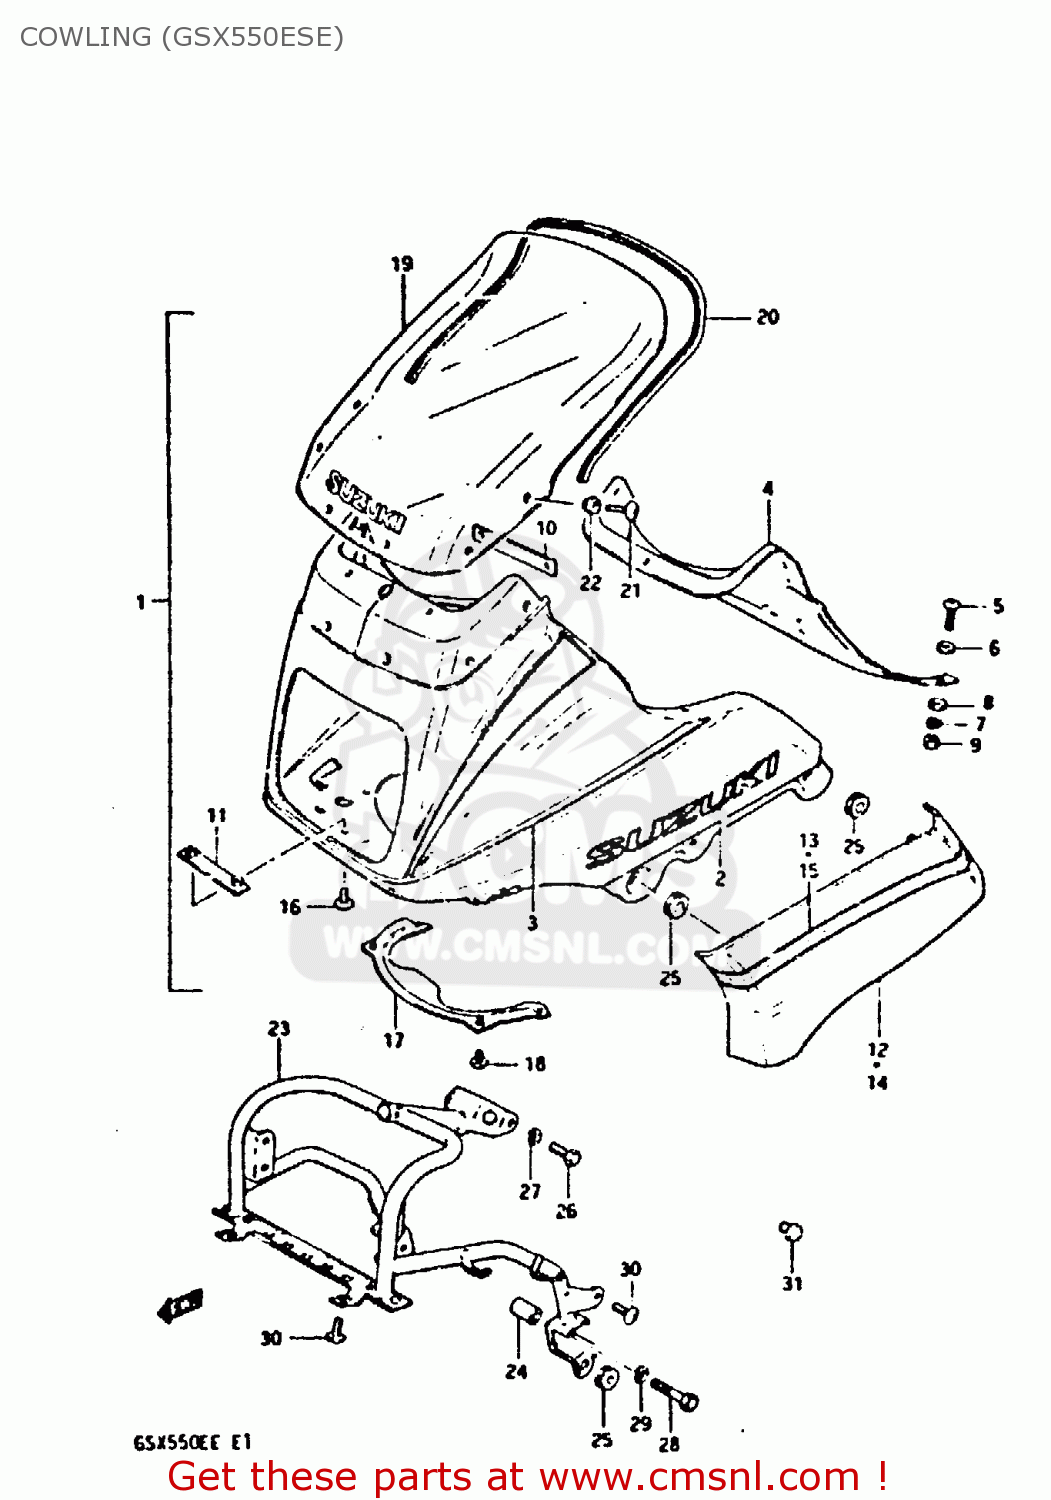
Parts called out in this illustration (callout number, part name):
1	COWLING ASSEMBLY
2	EMBLEM
3	TAPE SET
4	PANEL,COWLING,UPPER
5	SCREW
6	WASHER,5MM
7	LOCK WASHER
8	WASHER,5MM
9	NUT ,5MM
10	BRACKET,COWLING,UPPER
11	BRACKET,COWLING,LOWER
12	COVER,COWLING,RIGHT
13	TAPE SET
14	COVER,COWLING,LEFT
15	TAPE SET
16	SCREW
17	COVER,COWLING,LOWER
18	SCREW
19	WINDOW
20	MOLDING,LOWER
21	SCREW
22	CUSHION
23	BRACE,COWLING
24	SPACER (8.2X12.5X23.5)
25	CUSHION
26	BOLT
27	LOCK WASHER
28	BOLT
29	LOCK WASHER
30	SCREW 6X12
31	PLUG
